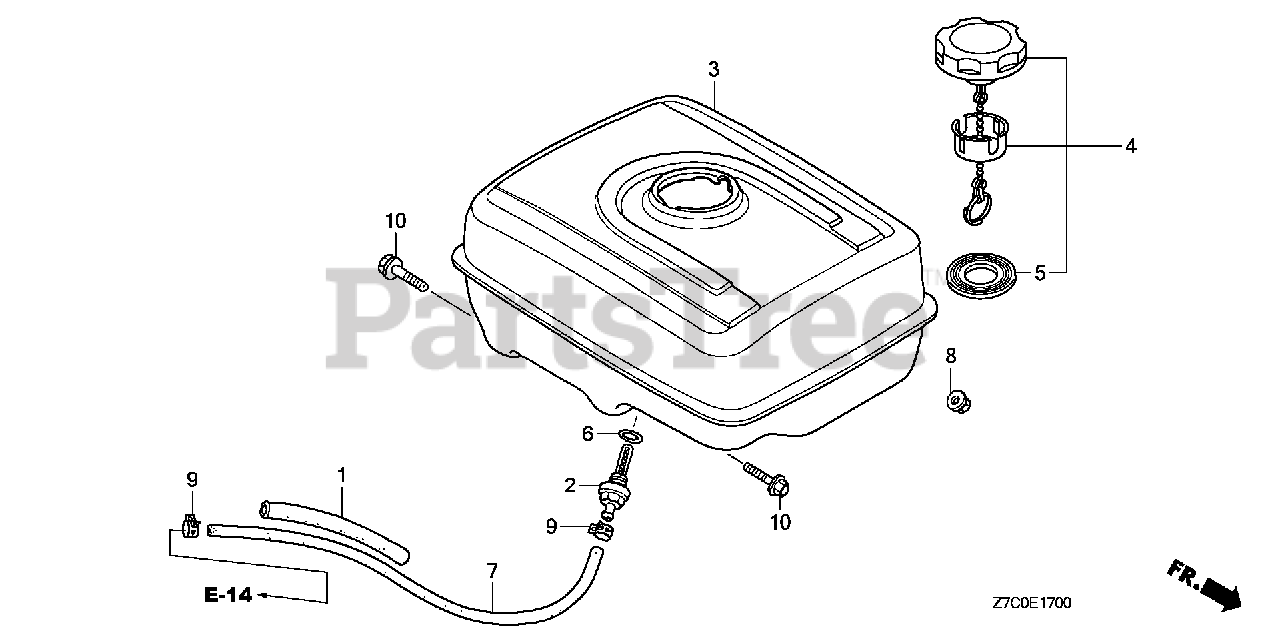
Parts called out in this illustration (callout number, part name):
1	RUBBER, SUPPORTER (107MM)
2	JOINT, FUEL TANK
3	TANK, FUEL *NH1* (BLACK)
3	TANK, FUEL *NH31* (MCKINLEY WHITE)
4	CAP, FUEL FILLER (CHROME PLATED)
4	CAP, FUEL FILLER
5	GASKET, FUEL FILLER CAP (39X62X3) (RADICON)
5	GASKET, FUEL FILLER CAP (39X62X3)
6	O-RING (13.5X1.5) (ARAI)
6	O-RING (14MM) (NOK)
7	TUBE, FUEL (4.5X222) (FKM)
8	NUT, FLANGE (8MM)
9	CLAMP, TUBE (D8)
10	BOLT, FLANGE (8X25)
